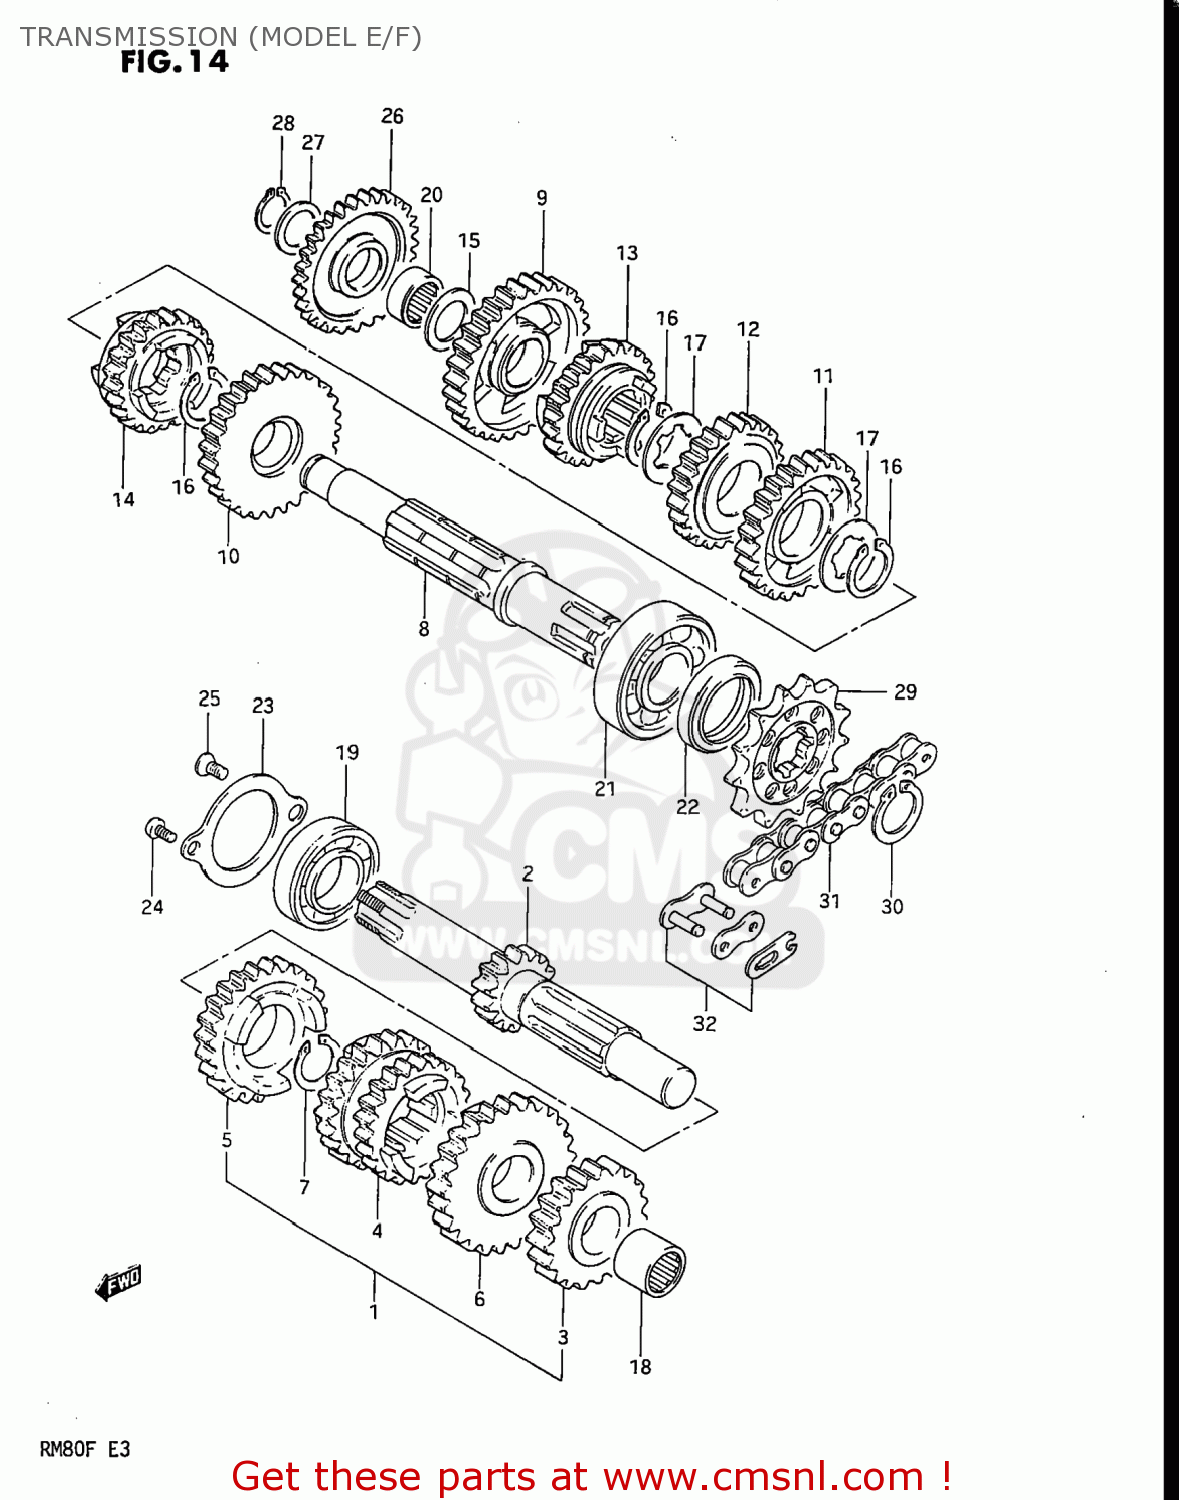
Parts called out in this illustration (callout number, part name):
1	SHAFT ASSEMBLY,COUNTER
2	SHAFT,COUNTER
3	GEAR,SECOND DRIVE
4	GEAR,THIRD & FOURTH DRIVE
5	GEAR,FIFTH DRIVE
6	GEAR,SIXTH DRIVE
7	CIRCLIP
8	SHAFT,DRIVE
9	GEAR,FIRST DRIVEN
10	GEAR,SECOND DRIVEN
11	GEAR,THIRD DRIVEN
12	GEAR,FOURTH DRIVEN
13	GEAR,FIFTH DRIVEN
14	GEAR,SIXTH DRIVEN
15	WASHER
16	CIRCLIP
17	WASHER,LOCK
18	ROLLER BEARING (13X19X1
19	BEARING(17X40X12)
20	BEARING(15X21X12)
21	BEARING
22	OIL SEAL (20X35X5)
23	RETAINER,CNTR SHAFT BEARING
24	SCREW
25	SCREW
26	GEAR,KICK STARTER IDLER(NT:26)
27	THRUST WASHER
28	CIRCLIP
29	SPROCKET,ENGINE
30	CIRCLIP
31	CHAIN ASSEMBLY,DRIVE
32	JOINT,CHAIN
